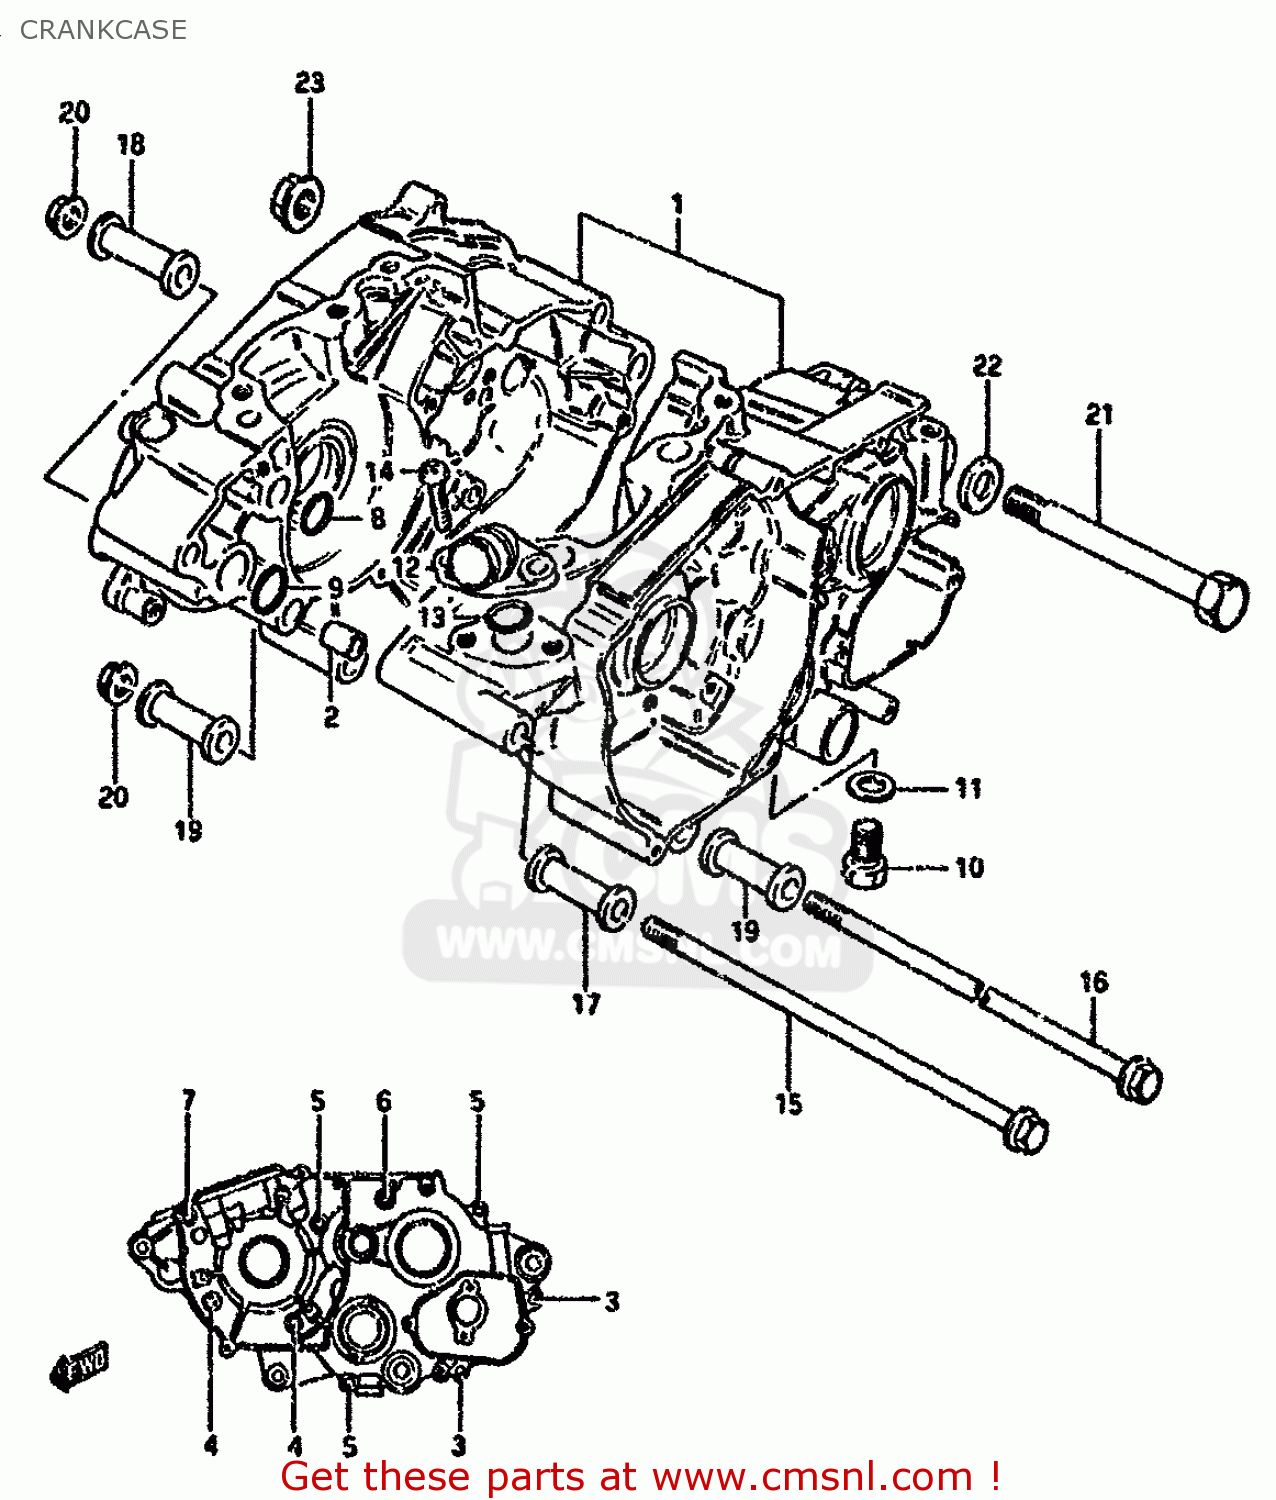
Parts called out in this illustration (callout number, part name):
1	CRANKCASE SET
2	PIN
3	SCREW
4	SCREW
5	SCREW
6	SCREW
7	SCREW
8	O-RING (D:2.4 ID:12.3)
9	O RING(D:2.4,ID:15.8)
10	BOLT
11	GASKET(10X14X3.6) (NAS)
12	CONNECTOR,WATER INLET
13	O RING(D:2.4,ID:15.8)
14	SCREW
15	BOLT(8X195)
16	BOLT (L:245)
17	SPACER,ENGINE MOUNT(L:32)
18	SPACER (L:42.1)
19	SPACER, ENGINE MOUNTING
20	NUT
21	BOLT,ENGINE MOUNT (12X98.5)
22	WASHER
23	NUT 12MM
